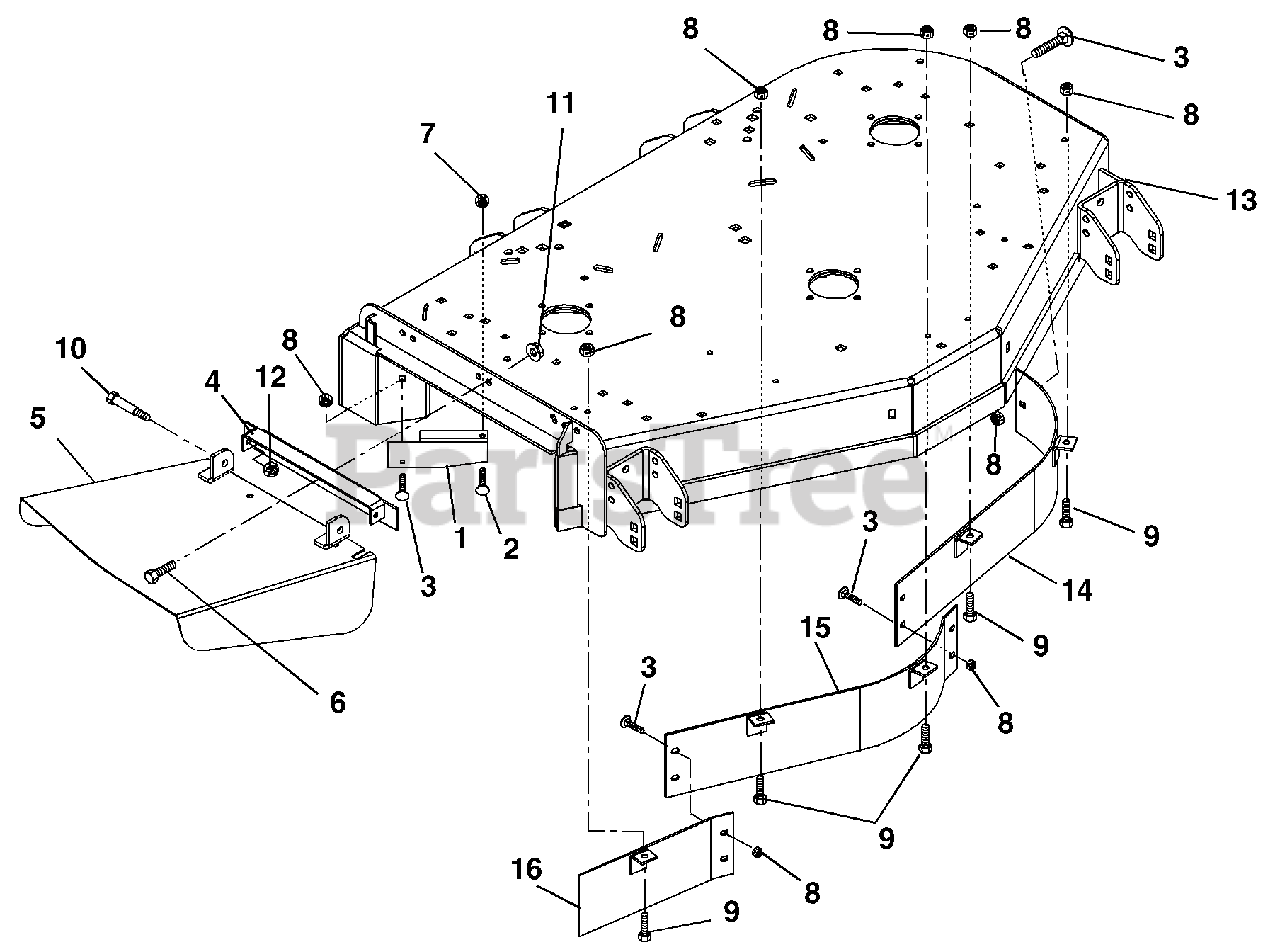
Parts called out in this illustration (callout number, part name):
1	Deflector- 60" (073, 075, 318, 319)
1	Deflector- 72" (074, 076)
2	Bolt-Round Head Square Neck .38-16 x .75 Grade 5
3	Bolt-Round Head Square Neck .31-18 x .75 Grade 5
4	Weldment, Discharge Chute Bracket
5	Chute-Discharge (073, 075, 318, 319)
5	Chute-Discharge (074, 076)
6	Bolt-Hex .38-16 x 1.00 Grade 5
7	Nut-Locking-Top-Flange .38-16
8	Nut, Locking-Top-Flange .31-18
9	Bolt, Hex .31-18 x .75 Grade 5
10	Bolt, Shoulder .38-16 x .50 Socket Head
11	Nut, Flange .375-16
12	Nut, Locking-Center .38-16
13	Weldment, 60" Mower Deck (073, 075, 318, 319)
13	Weldment, 72" Mower Deck- Float (074, 076)
14	Weldment, Upper Baffle Left 60" (073, 075, 318, 319)
14	Weldment, Baffle, Left Front-72" (074, 076)
15	Weldment, Baffle, Center Front 60" (073, 075, 318, 319)
15	Weldment, Baffle, Center Front 72" (074, 076)
16	Weldment, Baffle, Right Front 60" (073, 075, 318, 319)
16	Weldment, Baffle, Right Front 72" (074, 076)
